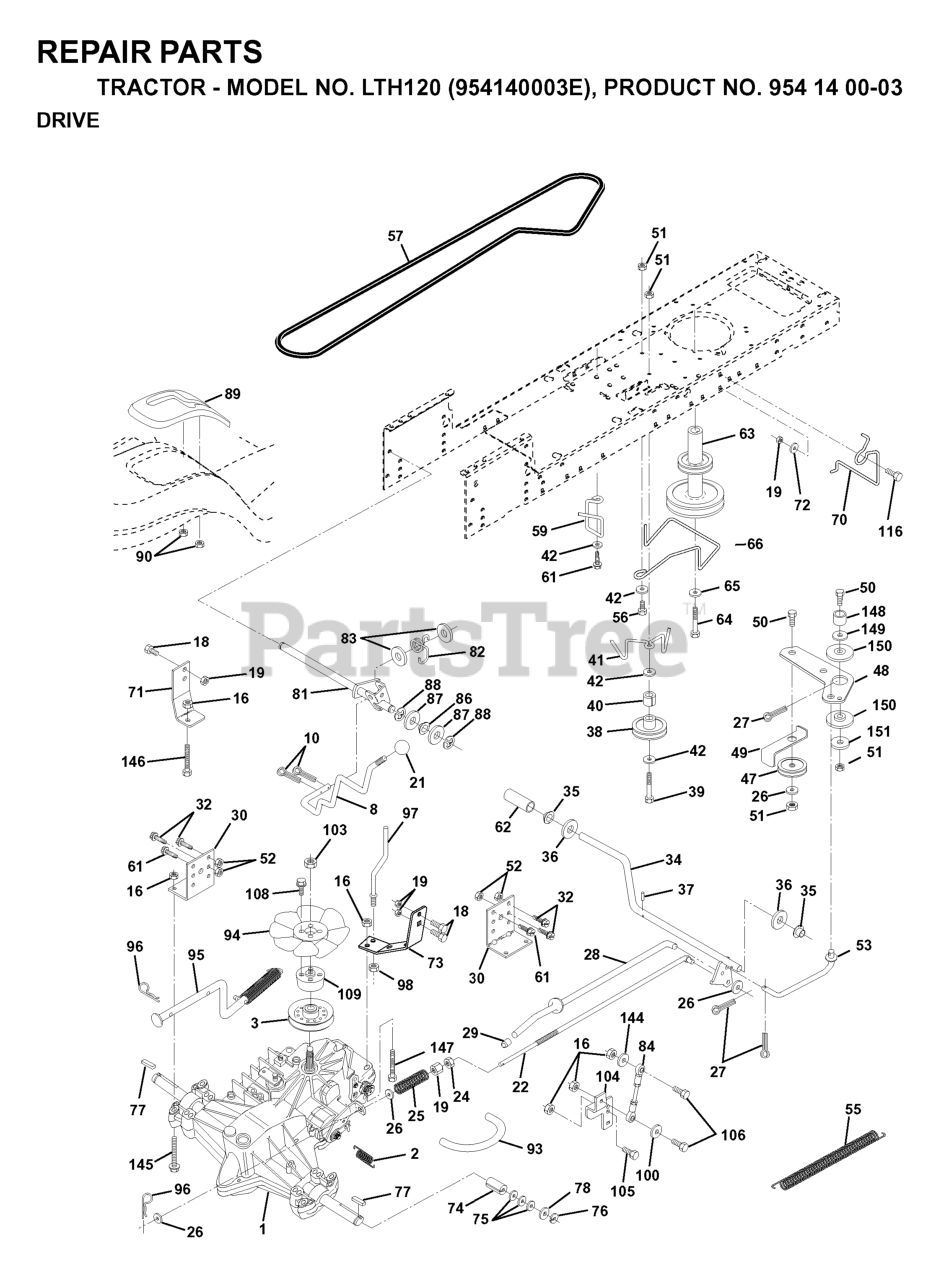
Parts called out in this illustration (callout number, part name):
1	AIR FILTER COVER ASSY
2	ELEMENT
3	ELEMENT
5	HOLDER AIR FILTER
6	BUCKLE ORANGE
8	CLAMP(F64)
9	HOSE
10	CLAMP(F96)
12	PLATE
13	PLATE CHOKE
20	CARBURETOR ASSY
